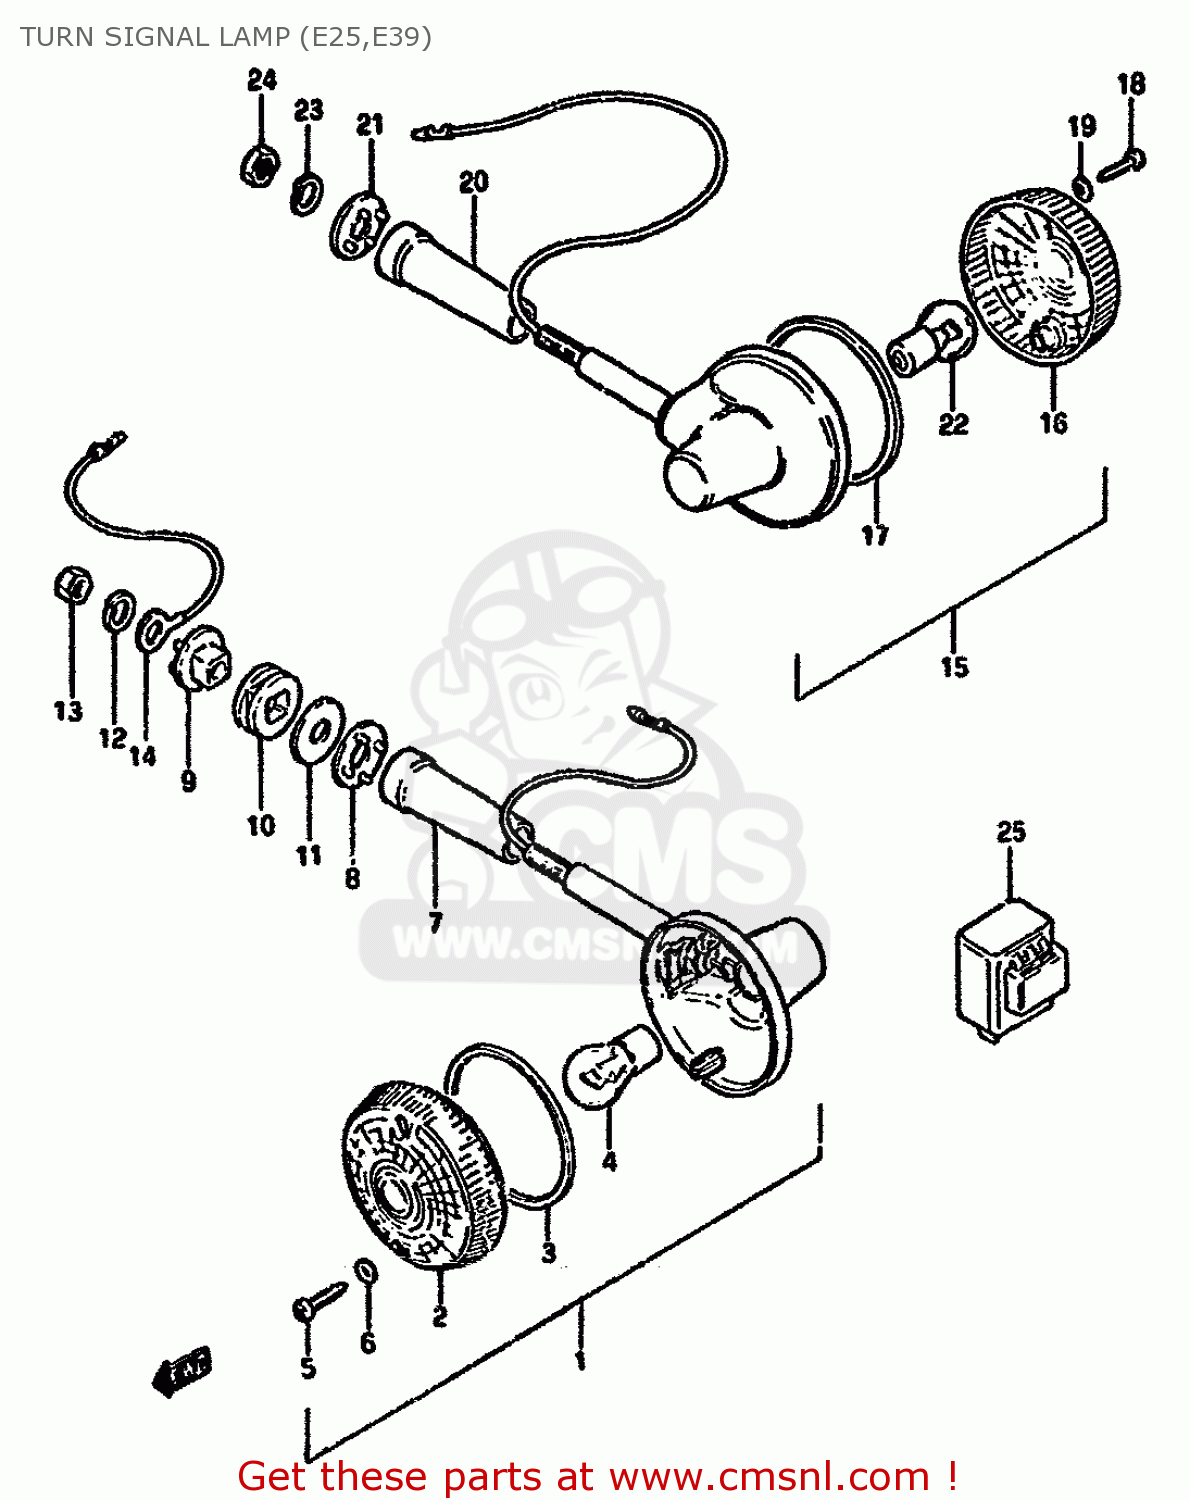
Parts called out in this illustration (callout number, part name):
1	LAMP ASSY,TURNSIGNAL
2	LENS
3	GASKET (NAS)
4	BULB(12V21W)
5	SCREW
6	GASKET (NAS)
7	COVER,STAY
8	SPACER
9	SPACER
10	CUSHION
11	WASHER (10.5X30X2.3)
12	WASHER,LOCK,10
13	NUT
14	LEAD WIRE,EARTH
15	LAMP ASSY,RR TURNSIGNAL
16	LENS
17	GASKET (NAS)
18	SCREW
19	GASKET (NAS)
20	COVER,STAY
21	SPACER
22	BULB(12V21W)
23	LOCK WASHER
24	NUT
25	RELAY ASSEMBLY,TURN SIGNAL
